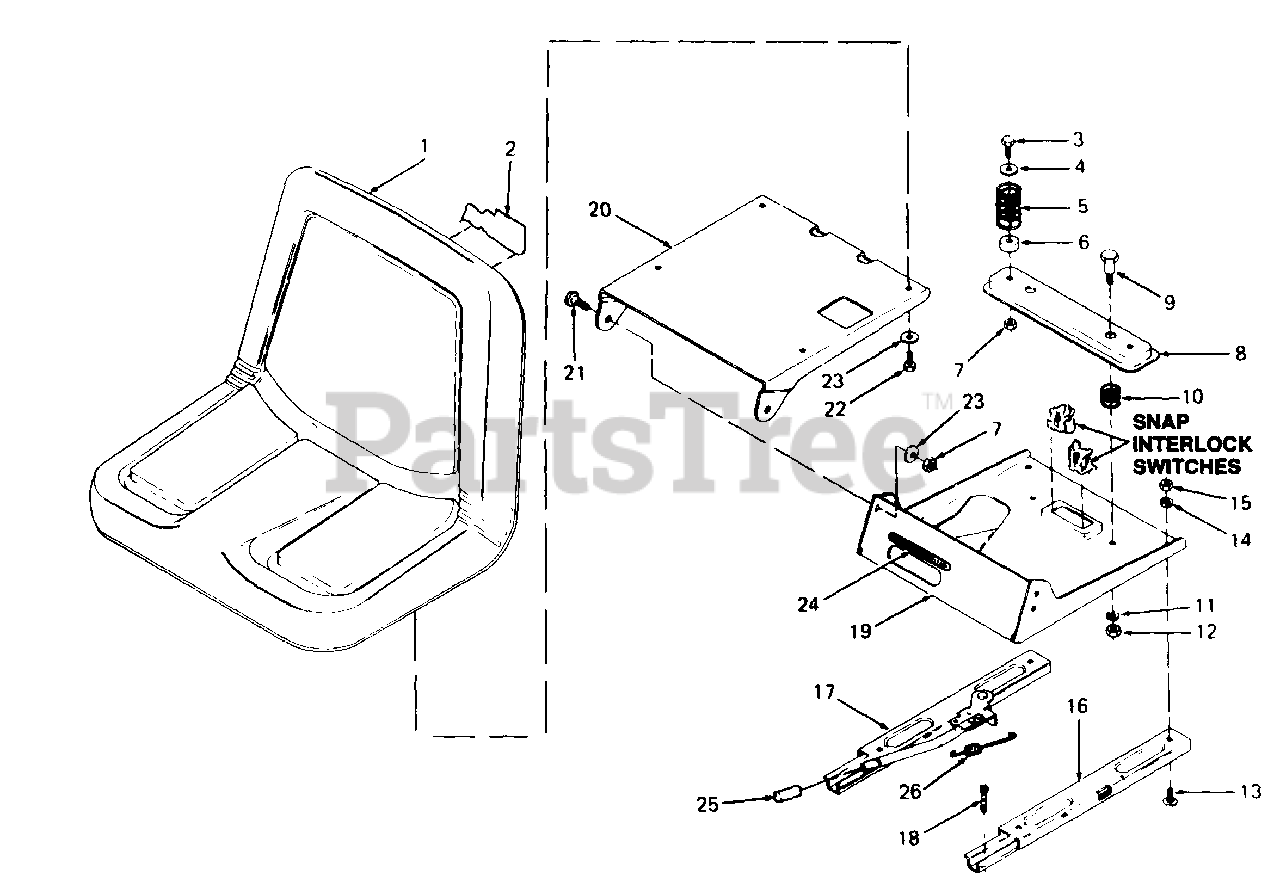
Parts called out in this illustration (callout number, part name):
1	Seat
2	Graphic, Made in USA
3	Screw, Hex Cap, 5/16-18 x .88 Lg GR5
4	Washer, Flat, .344 x .875 x .06 Thk
5	Spring, Comp, 1.28 OD x 2.18 Lg
6	Bushing, .930 OD x .50 Lg
7	Nut, Hex Center Lock, 5/16-18 GR5
10	Spring, Comp, 1.00 OD x .86 Lg
11	Washer, Lock, 3/8
12	Nut, Hex, 3/8-16 GR5
13	Bolt, Sht Nk Carriage, 5/16-18 x .62 LH
14	Washer, Lock, 5/16
15	Nut, Hex, 5/16-18 GR5
16	Slide, Seat - LH
17	Adjuster, Manual Seat - RH
18	Screw, Socket Hd Cap, 5/16-18 x 1.00 Lg
22	Screw, Hex Cap, 5/16-18 x .75 Lg GR5
23	Washer, Bell, .345 x .88 x .060 Thk
24	Label, Seat Adjustment
25	Cover, Handle
